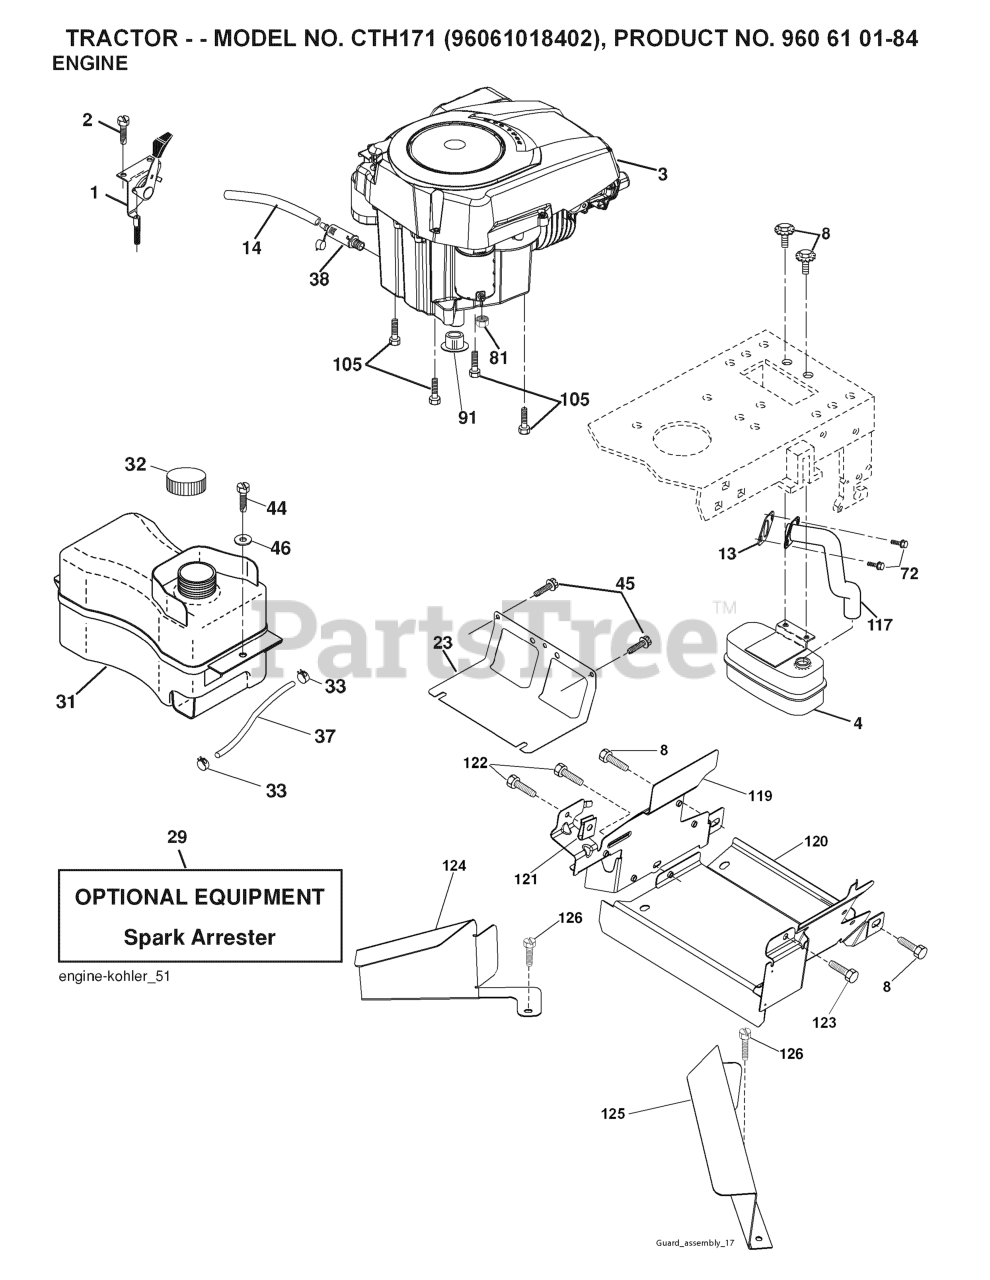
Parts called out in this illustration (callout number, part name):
1	CONTROL.TH/CK.C.
2	SCREW
4	MUFFLER.SINGLE.CYL.KOHL/B&S
8	BOLT.5/16-18UNCX3/4 W/SEMS.BLK
13	GASKET.EXHAUST.KOHLER
14	TUBE, DRAIN OIL ASM.
23	SHIELD.BROWNING.DBR.GUARD
29	KIT.SPARK ARRESTOR 794945 B&S
31	RP TANK FUEL FRT 1.5 GAL
32	FUEL CAP
33	HOSE CLAMP
37	LINE.FUEL.20
38	PLUG DRAIN OIL EASY
44	SCREW HEXWSHR 1/4-20X3/4
45	SCREW, 3/8-16X3/4
79	SCREW.SOCKET HD.5/16-1
81	NUT
91	BUSHING.1.375OD
105	SCREW 3/8-16X1
117	RP.TUBE.EXHAUST.KOHL.COURAGE
